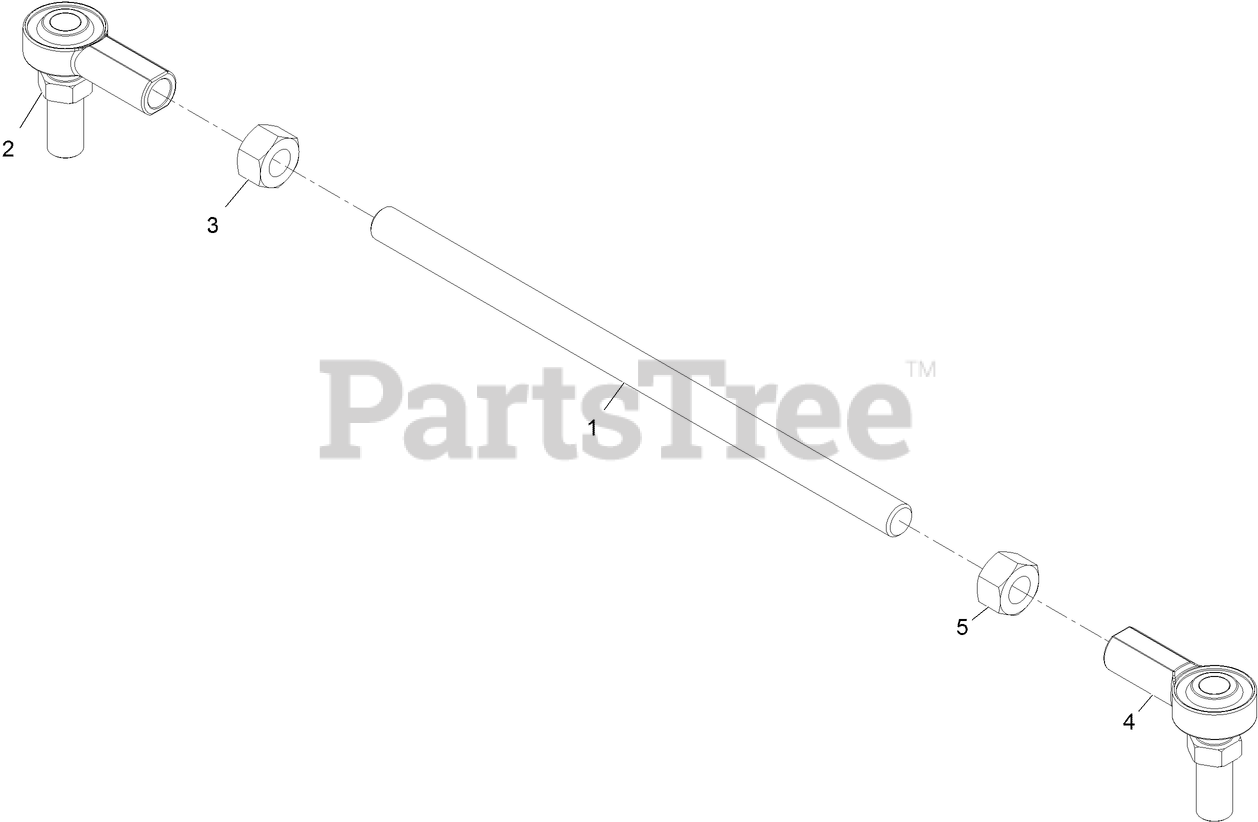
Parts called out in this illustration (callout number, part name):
1	ROD-LINKAGE, STEERING
2	ROD-END, RH
3	NUT-HEX
4	ROD-END, LH
5	NUT-HEX, LH
